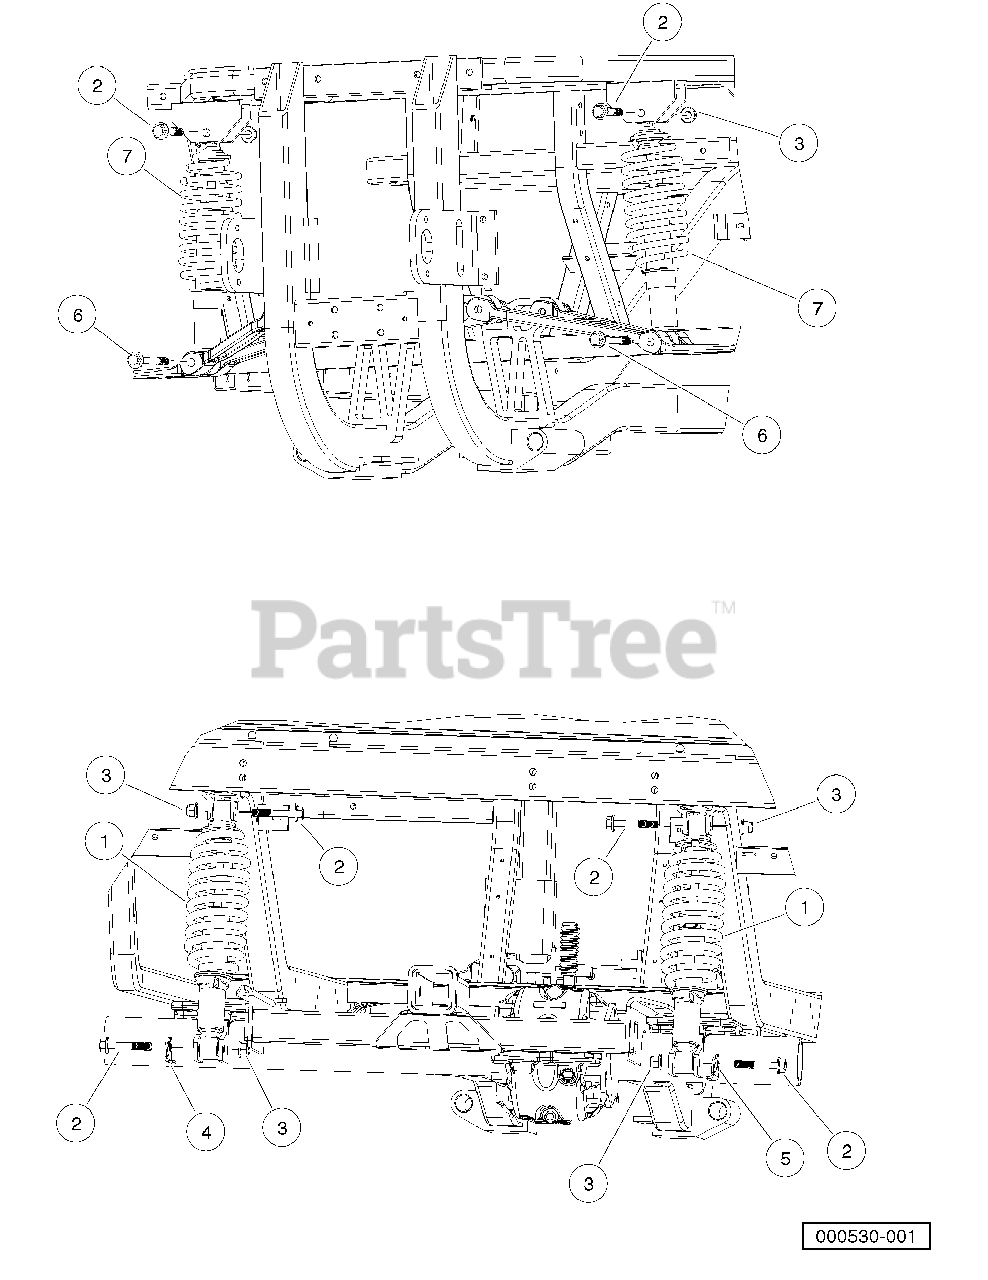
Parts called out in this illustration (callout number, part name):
1	Shock, Coil Over Rear
2	Bolt, Flange Head, M12 X 1.75 X 70
3	Nut Flg, M12x1.75, Nylon Gr 10
4	Brkt, Line, Hyd, Shk Mnt, Drv
5	Brkt, Line, Hyd, Shk Mnt, Pass
6	Bolt Flg, M12x1.75x100, Patch
7	Asm, Coil & Shock, Frt
